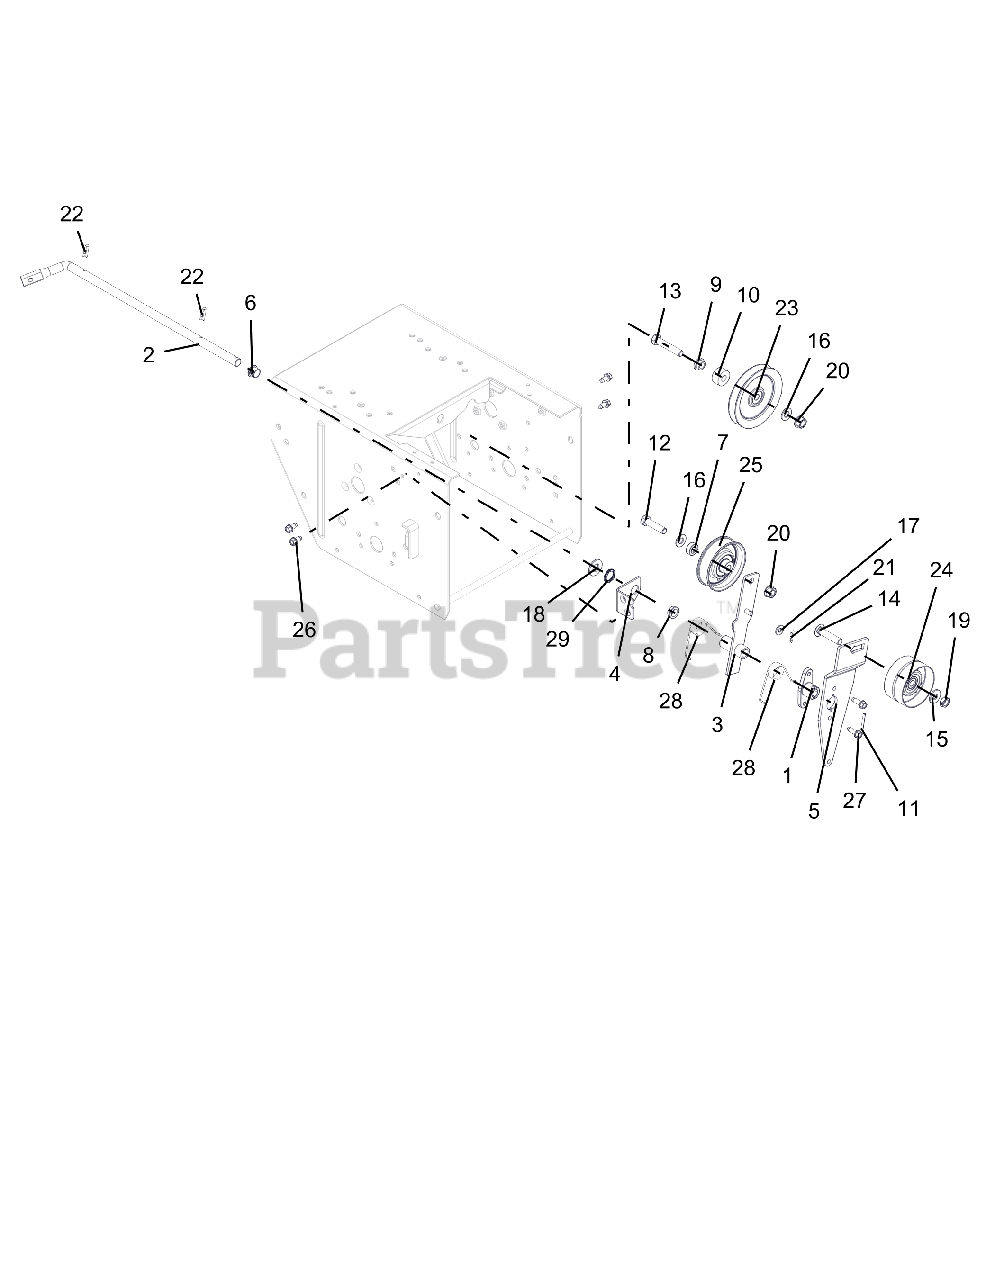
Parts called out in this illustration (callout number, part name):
1	HUB, BRAKE ARM
2	ARM, ATTACHMENT-BLACK
3	ARM, TRACTION CLUTCH
4	BRKT, SUPPORT
5	ARM, IDLER ATTACHMENT
6	BUSHING, POLYLINER - .50 SPLIT
7	BSHG, FLG .315X.500X.358X.281
8	BSHG, FLANGE .500 x .625 x .270 x .750
9	BSHG, FLANGE .391x.56x.313x.75
10	BSHG, POCKET .391X.570X1.0X.450
11	PIN, ROLL .125 X 1.00
12	BLT-HEX .38-16X1.50 GR5 YWZC
13	BLT-HEX .38-16X2.00 GR5 YWZC
14	BLT-RHDSSQNK .38-16X1.75 G5YZ
15	WSHR-FL-STL.38X.875X.083 YWZC
16	WSHR-FL-STL.406X.812X.065 YWZ
17	WSHR-FL-STL.281X.62X.065 YWZC
18	WSHR-FL-STL.531X1.06X.095YWZC
19	@NUT-LK-CTR-JAM .375-16 YWZC
20	NUT, LK-TOP-FLG .38-16 YWZC
21	PIN-HAIR INT .06X.18X.77
22	CLIP, SPRING
23	SHEAVE, IDLER -V .38 x 4.00
24	IDLER, FLAT -2.75 OD X .375 ID
25	IDLER, FLAT - 3.05" X .75"
26	SCR-TAP .25-20X.50 HWH TR YWZ
27	SCR-TAP .25-20X.75 HWH TR YWZ
28	SPRG, TORSION
29	WAVE, SPRING .600x.875x.25FH
